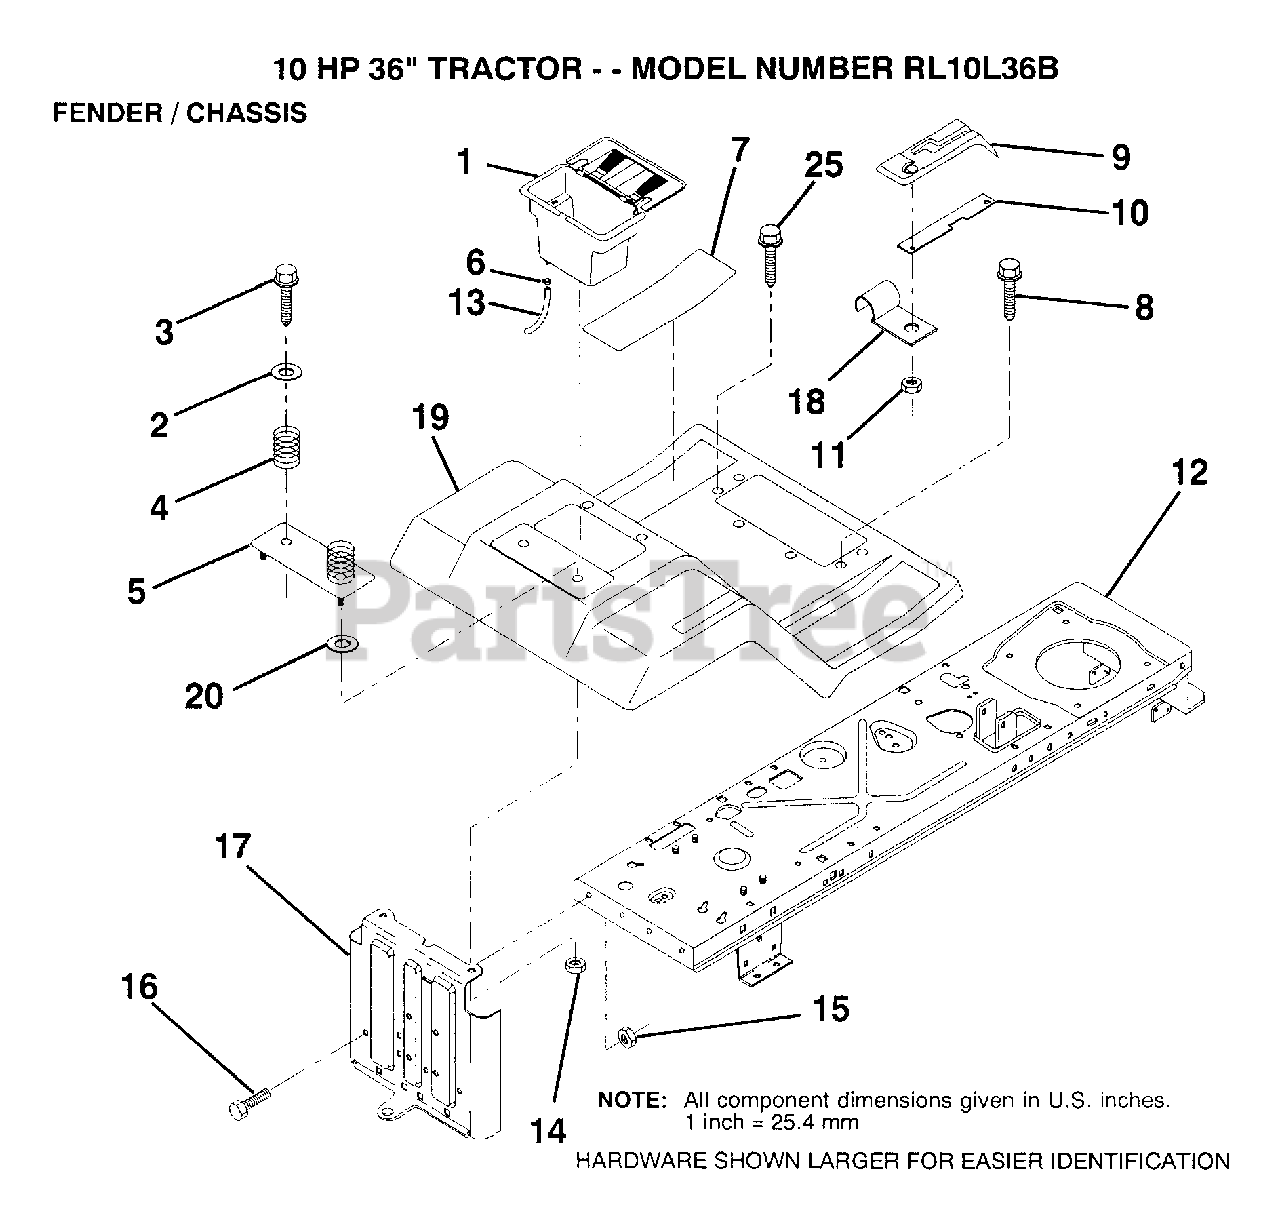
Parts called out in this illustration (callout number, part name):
2	WASHER
3	SCREW
4	SPRING COMPRESSIO
5	"PLATE, BATTERY"
6	HOSE CLAMP T
7	PAD FOOTREST
8	SCREW
9	CONSOLE SHFT 4SP
11	NUT
13	TUBE T
14	NUT
16	BOLT
17	DRAWBAR
18	"CLIP,INSULATOR"
